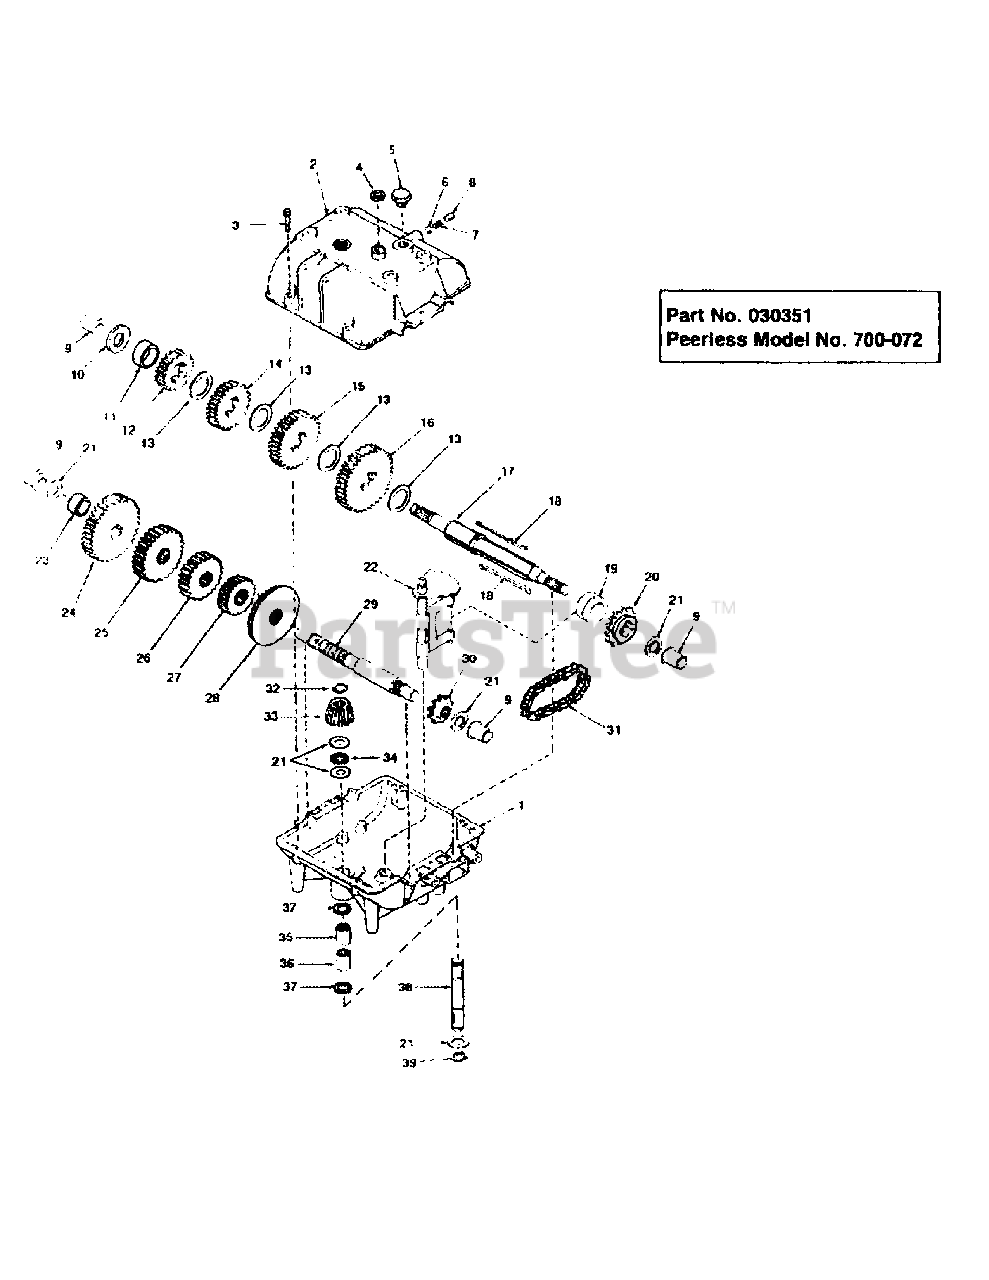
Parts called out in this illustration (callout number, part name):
1	transmission case
2	transmission cover
3	cap screw
4	seal, square cut
5	threaded plug
6	steel ball, 5/16" dia
7	spring
8	set screw
9	flange bushing
10	thrust washer
11	spacer
12	spur gear (30 teeth)
13	thrust washer
14	spur gear (32 teeth)
15	spur gear (35 teeth)
16	spur gear (37 teeth)
17	shaft-output/brake
18	key, shift
19	shift collar
20	sprocket (18 teeth)
21	thrust washer
22	rod & fork, shift
23	spacer
24	spur gear (20 teeth)
25	spur gear (18 teeth)
26	spur gear (15 teeth)
27	spur gear (12 teeth)
28	spur gear (42 teeth)
29	counter shaft
30	sprocket (9 teeth)
31	roller chain (#41, 24 links)
32	retaining ring
33	bevel pinion, input
34	thrust bearing
35	needle bearing
36	needle bearing
37	o-ring
38	input shaft
39	retaining ring
